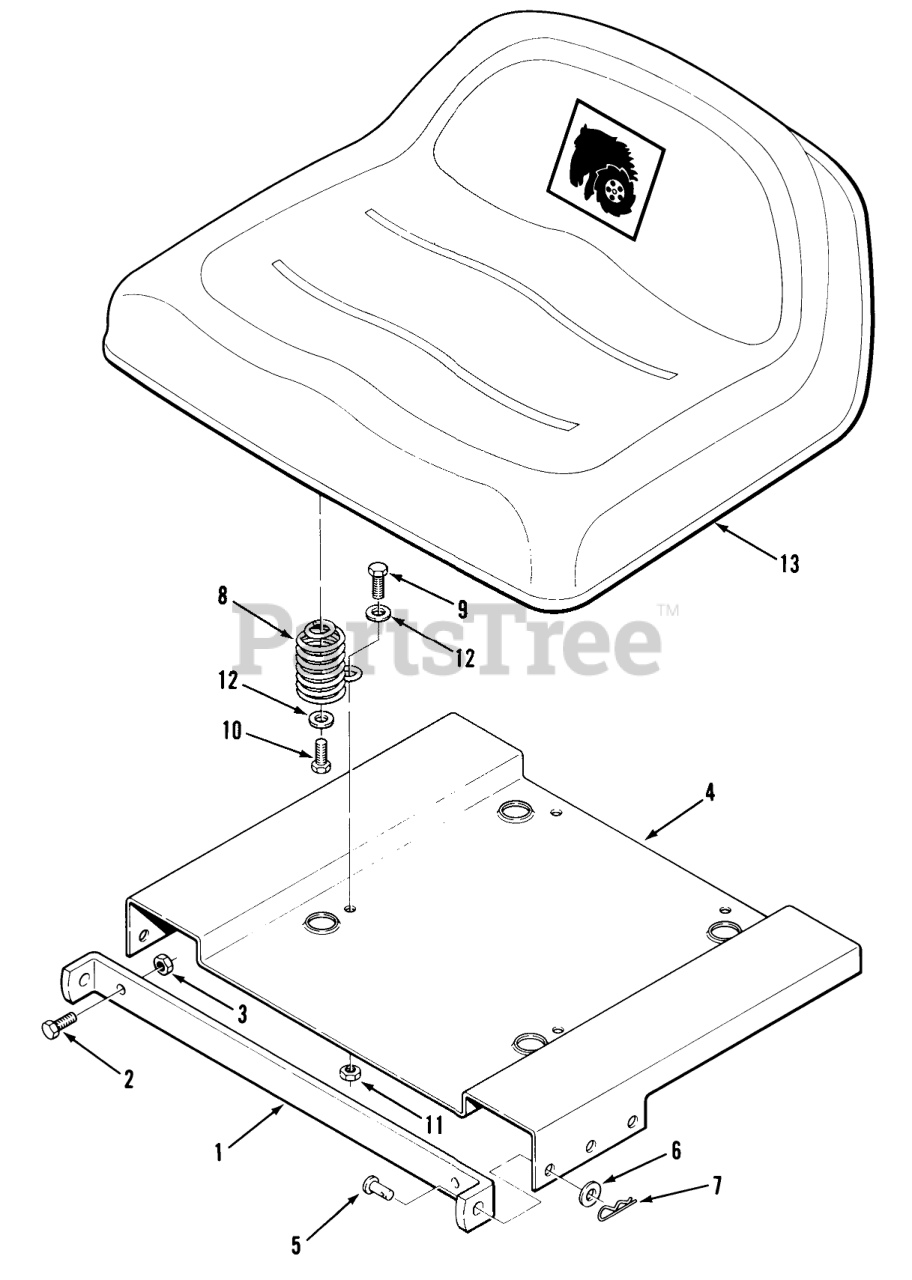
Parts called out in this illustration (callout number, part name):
1	Seat Mounting Bracket
2	Bolt
3	Nut
4	Seat Pivot Plate
6	Washer
7	Hairpin
8	Spring
9	Bolt
10	Bolt
11	Nut
12	WASHER 5/16 SAE
13	ASSY-SEAT
